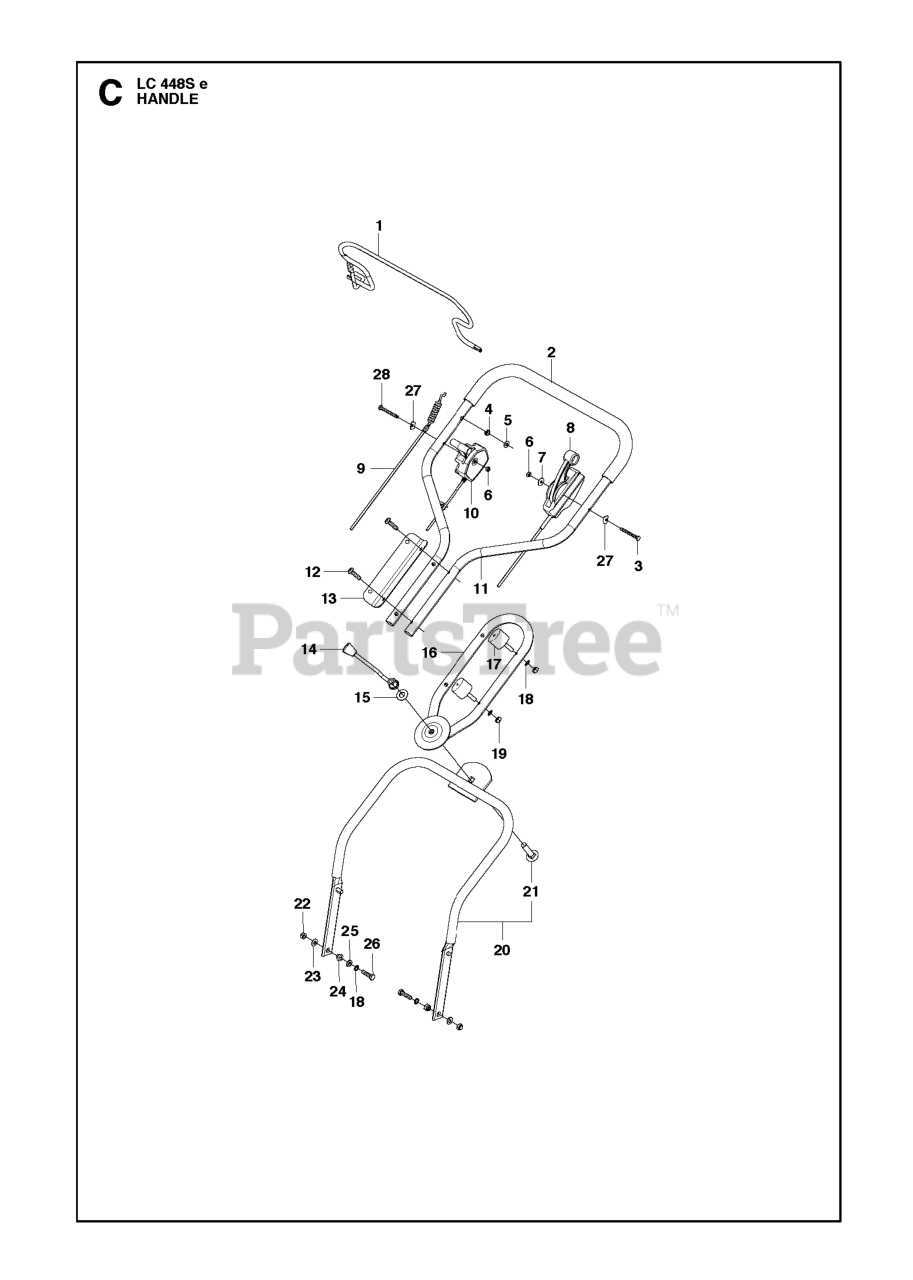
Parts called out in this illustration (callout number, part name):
3	SCREW M6X55
6	NUT FLANGE - M6
19	NUT
22	LOCKNUT M8
